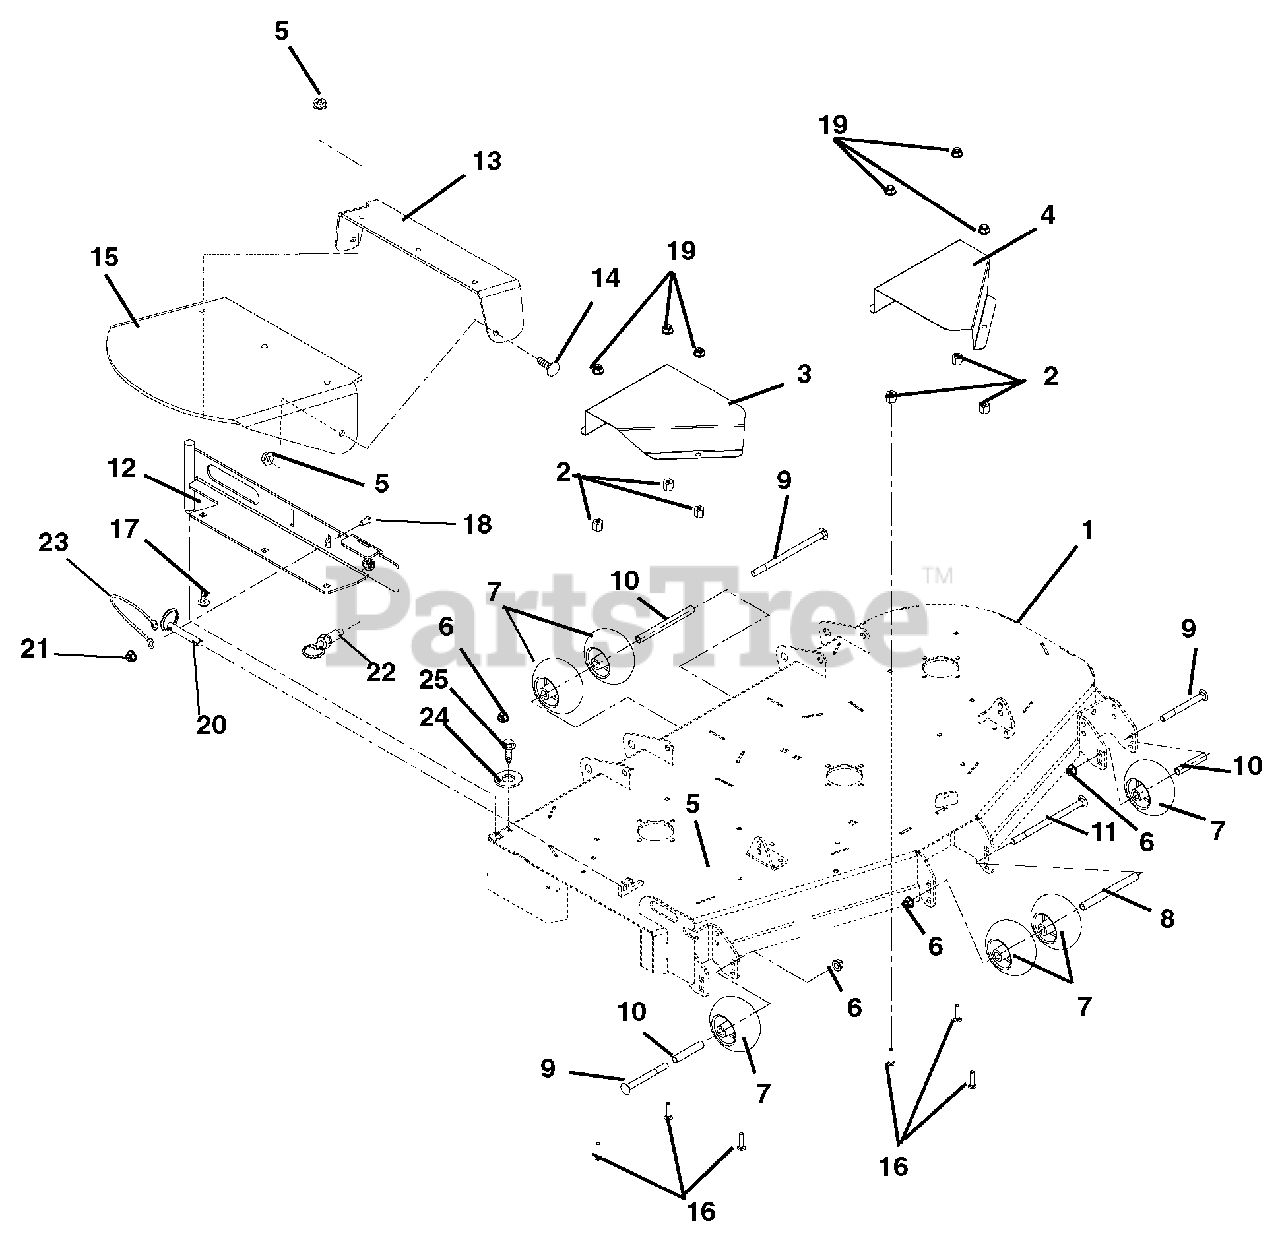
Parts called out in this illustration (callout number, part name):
1	WMT,60" SIDE DISCH DECK,10GA
1	WMT,52" SIDE DISCH,10GA,ORANGE
1	WMT,48" SIDE DISCH,10GA,ORANGE
2	NUT-HEAVY HEX .38-16 YWZC
3	60" RH BELT GUARD
3	GUARD-44-52 RH SPINDLE SHEAVE
4	60" LH BELT GUARD
4	44-52" LH DECK BELT GUARD
5	@NUT-LK-NYL-FLG .38-16 YWZC
6	@NUT-LK-NYL-FLG .50-13 YWZC
7	ANTI-SCALP WHEEL - 5X3 CTR
8	SPACER, .510X.625X6.50
9	BLT-RDHDSQNK .50-13X5.00 GR5YZ
10	SPACER, .510X.625X3.35
11	@BLT-RDHDSQNK .50-13X8.50 G5YZ
12	WMT, 52"-60" DISCH CHUTE MTG
12	44"-48" DISCH CHUTE MTG WMT-RD
13	SUPPORT, RUBBER DISCH CHUTE
14	@BLT-RDHDSQNK .38-16X1.00 G5YZ
15	CHUTE, RUBBER DISCHARGE
16	@BLT-HEX .38-16X1.25 GR5 YWZC
17	@BLT-RDHDSQNK .38-16X1.25 G5YZ
18	@BLT-HEX .25-20X.75 GR5 YWZC
19	@NUT-SPNLK-FLG .375-16 YWZC
20	PIN, SPRING BALL .375OD X 1.50
21	@NUT-LK-TOP-FLG .25-20 YWZC
22	PULL PIN,.50-13THDX.310 PLNGR
23	CABLE, 6.0 LANYARD, NYLON
24	BUMPER,RECESSED1.50X.63 W/.31
25	@SCR-TAP .31-18X.75 HWH TR YWZ
